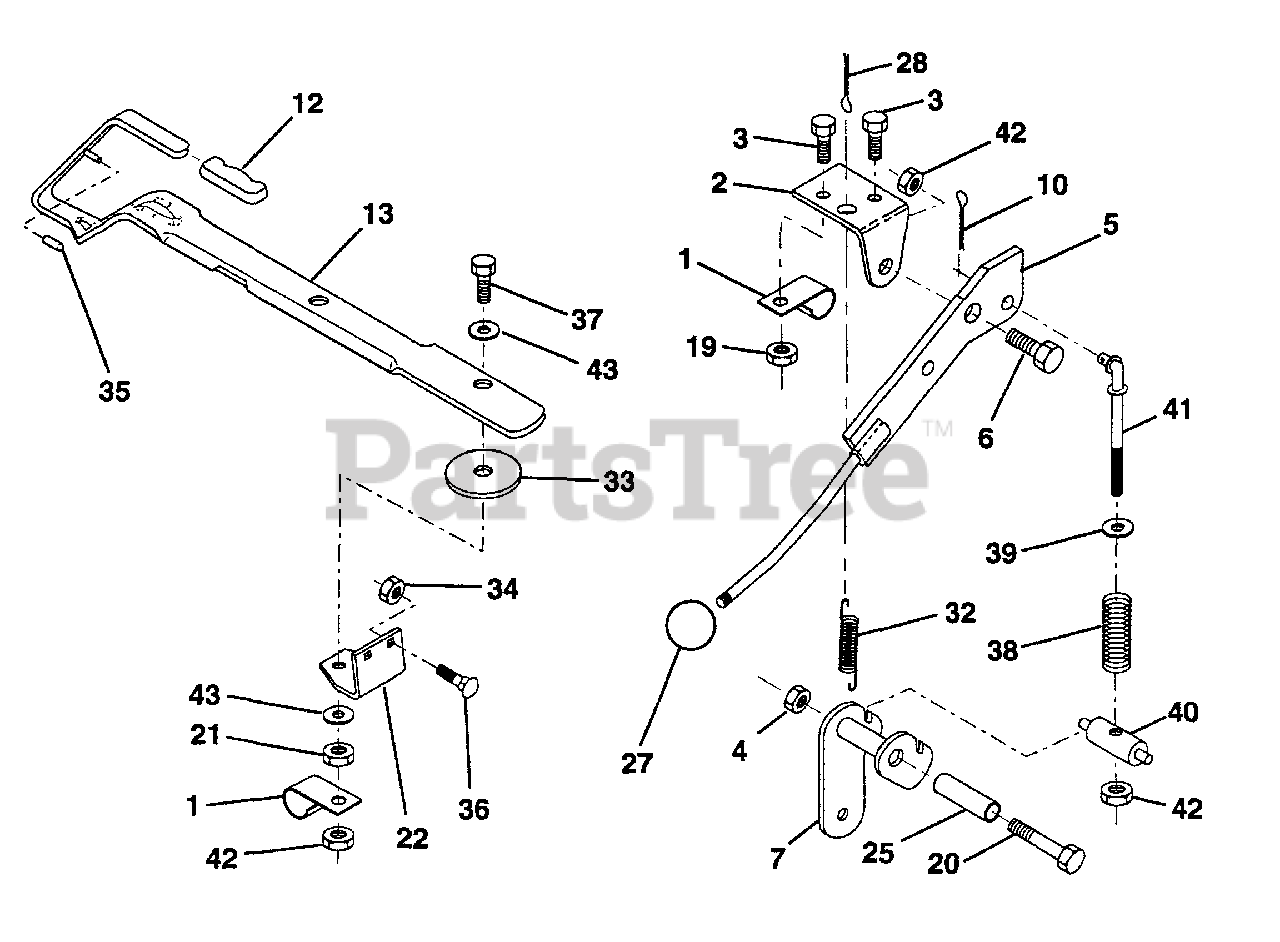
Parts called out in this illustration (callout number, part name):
1	Clip, Insulated
2	Bracket, Mower Clutch
3	Bolt, Hex Hd, Fin. 1/4-20 UNC x 1/2 Gr. 5
4	Nut, Crownlock 3/8-16
5	Assembly, Clutch Lever
6	Bolt, Shoulder
7	Assembly, Mower Clutch Arm
10	Pin, Cotter 1/8 x 3/4
12	Handle, Lift Lever
13	Assembly, Lift Handle
19	Nut, Crownlock 1/4-20
20	Bolt, Hex Hd, Fin. 3/8-16 UNC x 2-3/4
21	Nut, Centerlock
22	Bracket, Lift Lever
25	Tube, Spacer
28	Pin, Cotter 3/32 x 3/4
32	Spring, Extension, Return
33	Washer .390 x 1.437 x .074
34	Nut, Crownlock 5/16-18
35	Cap, Vinyl, Red
36	Bolt, Carriage 5/16-18 x 3/4
37	Bolt, Hex Head 3/8-16 UNC x 1-1/2
38	Spring, Compression
39	Washer 13/32 x 1 x 11 Gauge
40	Trunnion, Threaded 3/8-16
41	Rod, Tension, Clutch
42	Nut, Crowniock 3/8-16 UNC
43	Washer 25/64 x 1-1/4 x 12 Gauge
